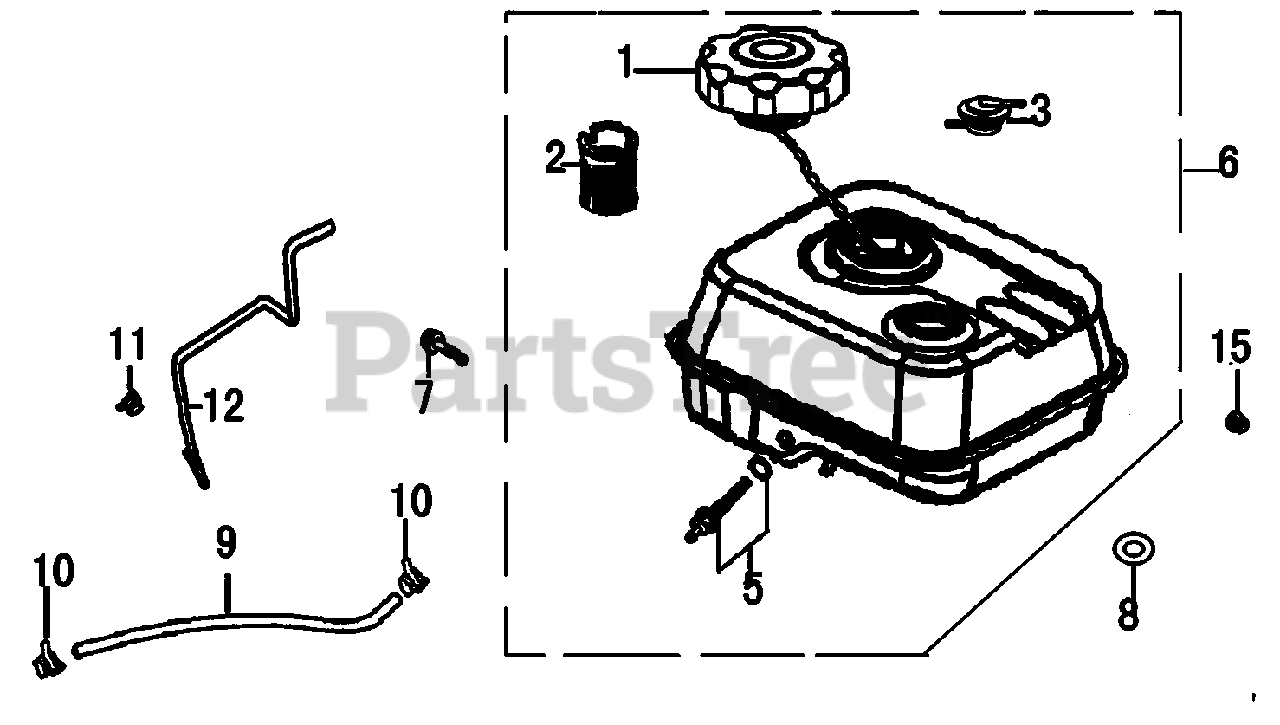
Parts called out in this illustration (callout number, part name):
1	CAP COMP, FUEL FILLER
2	FILTER, FUEL
3	GAS VALVE, FUEL TANK
5	JOINT ASSY, FUEL TANK
6	TANK ASSY, FUEL
7	BOLT, FLANGE 8x25
8	WASHER, RUBBER
9	HOSE, FUEL
10	CLAMP/COLLAR
12	HOSE, ROV TO AIR CLEANER
15	NUT, FLANGE
